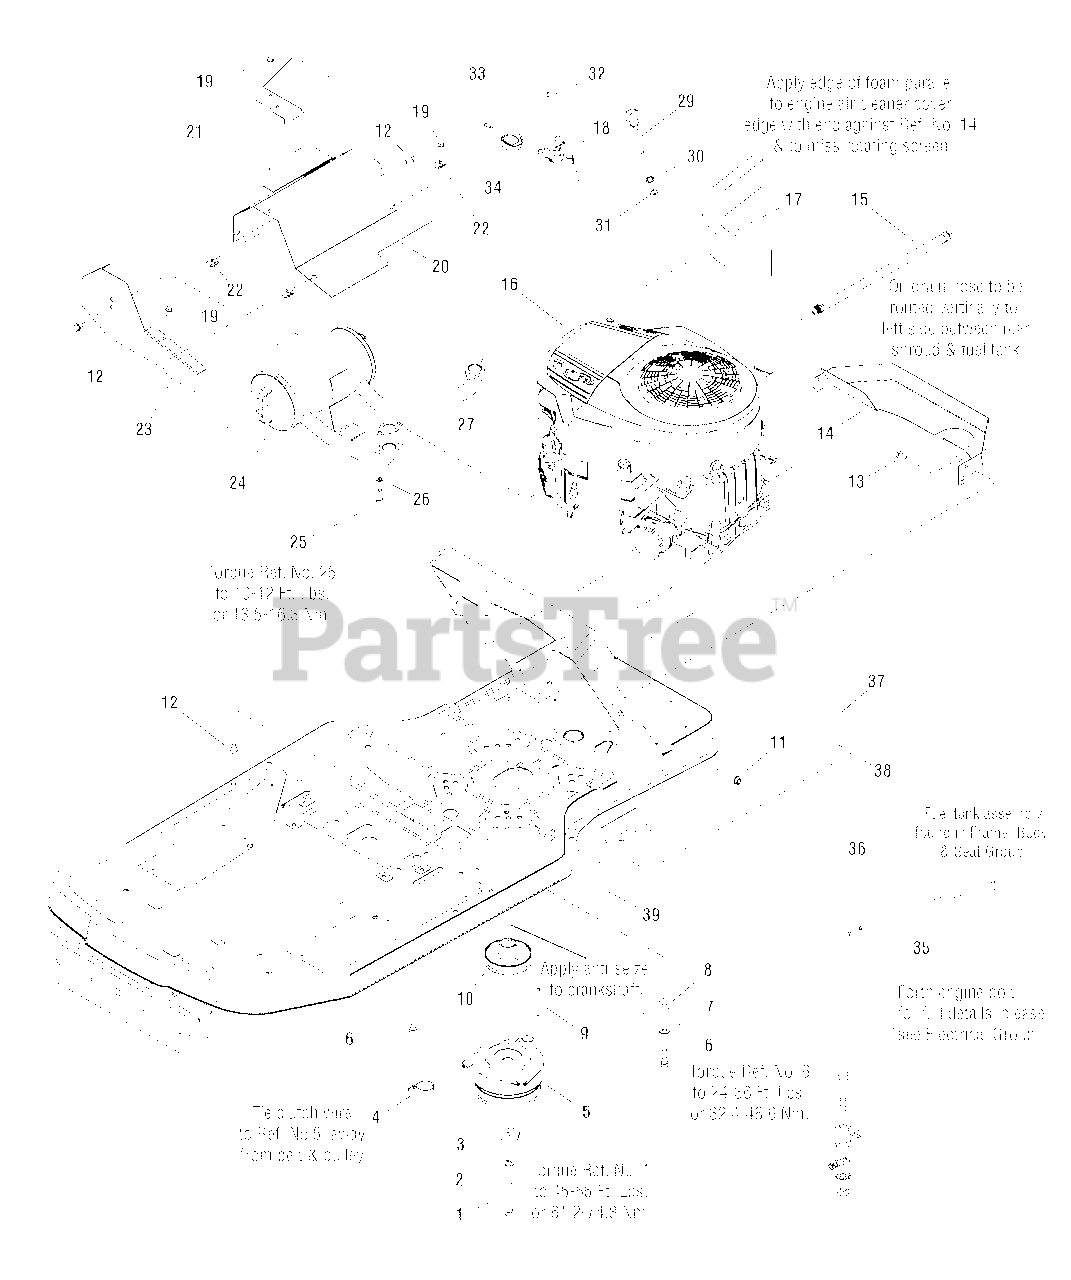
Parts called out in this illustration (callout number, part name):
1	CAPSCREW, Hex Head, 7/16-20 x 2-3/4, G5
2	LOCKWASHER, Spring
3	WASHER, Hex, 7/16
4	TIE, Self-Locking, 3.62"
5	CLUTCH, Electric Ogura
6	SCREW, Hex Washer Head Taptite, 3/8-16 x 1-1/4
7	WASHER, 3/8
8	RETAINER, Clutch
9	KEY, Hi-Pro, 1/4 x 2-1/2
10	PULLEY ASSEMBLY, Engine
11	NUT, Hex Whiz Lock Flange, 5/16-18
12	SCREW, Hex Washer Head Taptite, 5/16-18 x 1/2
13	CAPSCREW, Hex Head, 5/16-18 x 3/4, G5
14	AIR DUCT, Inlet
15	HOSE, Oil Drain, 16.5"
16	*ENGINE, 24HP Briggs & Stratton
17	SEAL, Foam Air Inlet
18	THROTTLE ASSEMBLY
19	SCREW, Hex Whiz Lock Flange, 1/4-20 x 5/8
20	HEAT SHIELD, Muffler Top
21	HEAT SHIELD, Throttle
22	NUT, Speed, 1/4-20
23	HEAT SHIELD, Muffler Side
24	MUFFLER, 24HP V-Twin ELS
25	CAPSCREW, Hex Head, 5/16-18 x 3/4, G8
26	LOCKWASHER, Spring, 5/16
27	GASKET, Exhaust
28	DECAL, Hot Exhaust
29	CABLE, Choke
30	WASHER, Lock Internal Tooth, 3/8
31	NUT, Hex, 3/8
32	SCREW, Taptite Pan Head Torx, 1/4-20 x 5/8
33	SCREW, Taptite Pan Head Combo, #10-16 x 3/4
34	KNOB, Throttle
35	HOSE, Fuel, 19.5"
36	CLAMP, Hose
